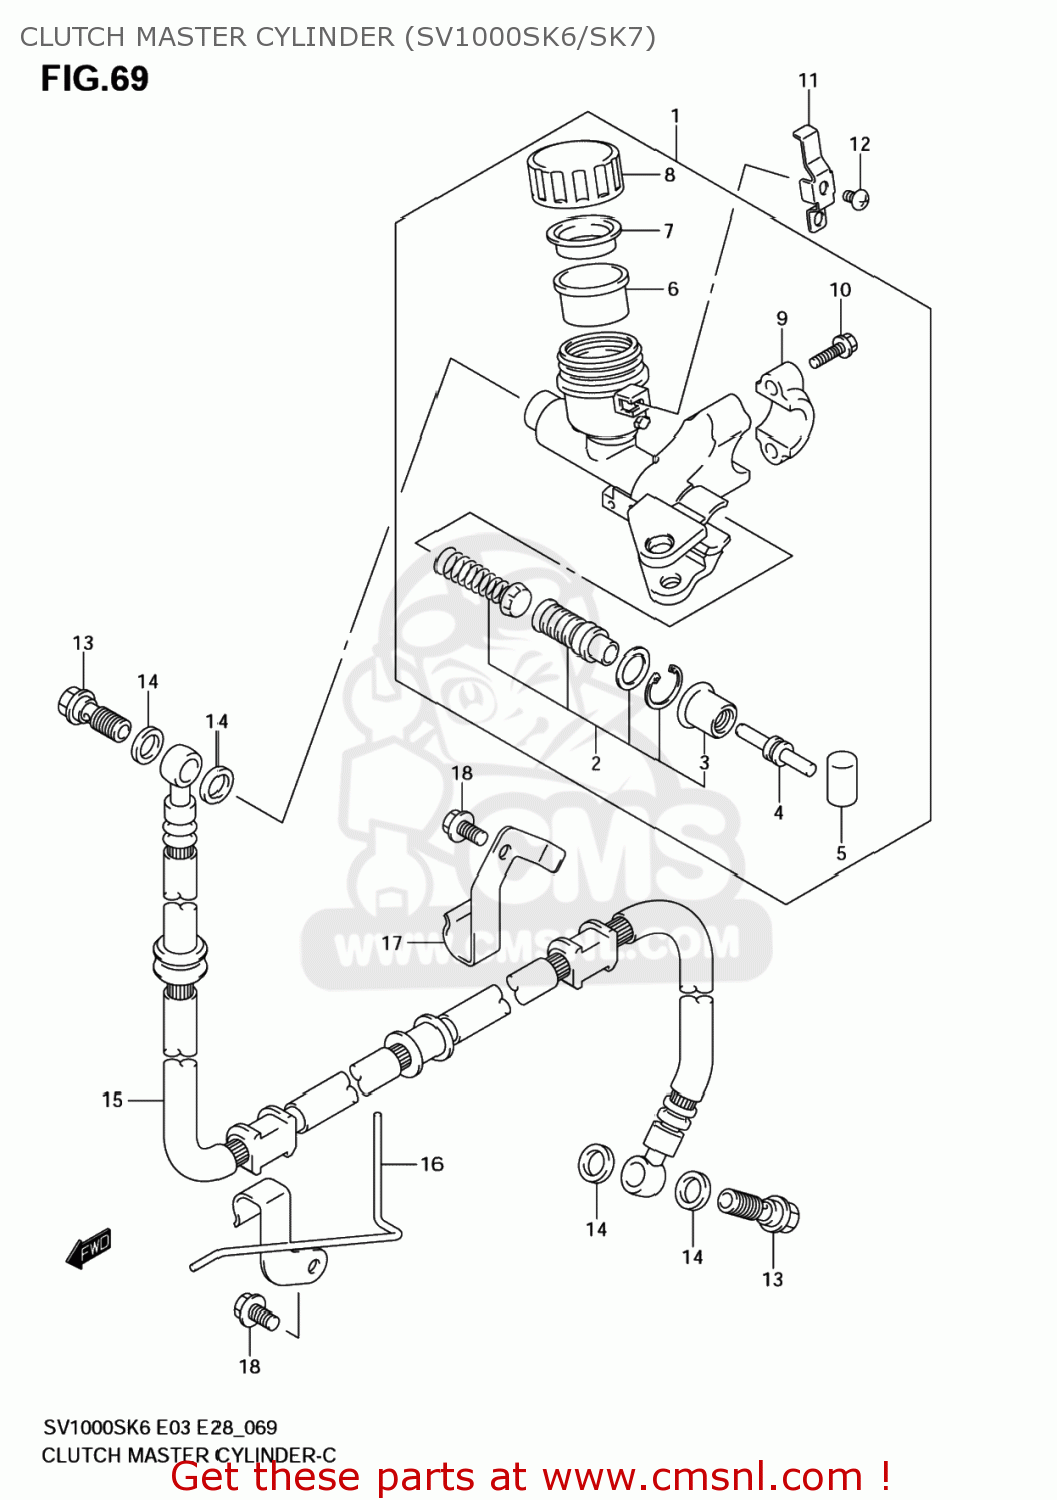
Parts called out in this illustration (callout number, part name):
1	CYLINDER ASSY, CLUTCH MASTER
2	PISTON & CUP SET
3	BOOT
4	PUSH ROD
5	BUSH
6	DIAPHRAGM
7	PLATE
8	CAP
9	HOLDER
10	BOLT(6X22)
11	PLATE,RESERVOIR TANK CAP
12	SCREW
13	BOLT UNION
14	WASHER(10X15X1.5)
15	HOSE,CLUTCH
16	CLAMP,CLUTCH HOSE
17	CLAMP,CLUTCH HOSE NO.2
18	BOLT
